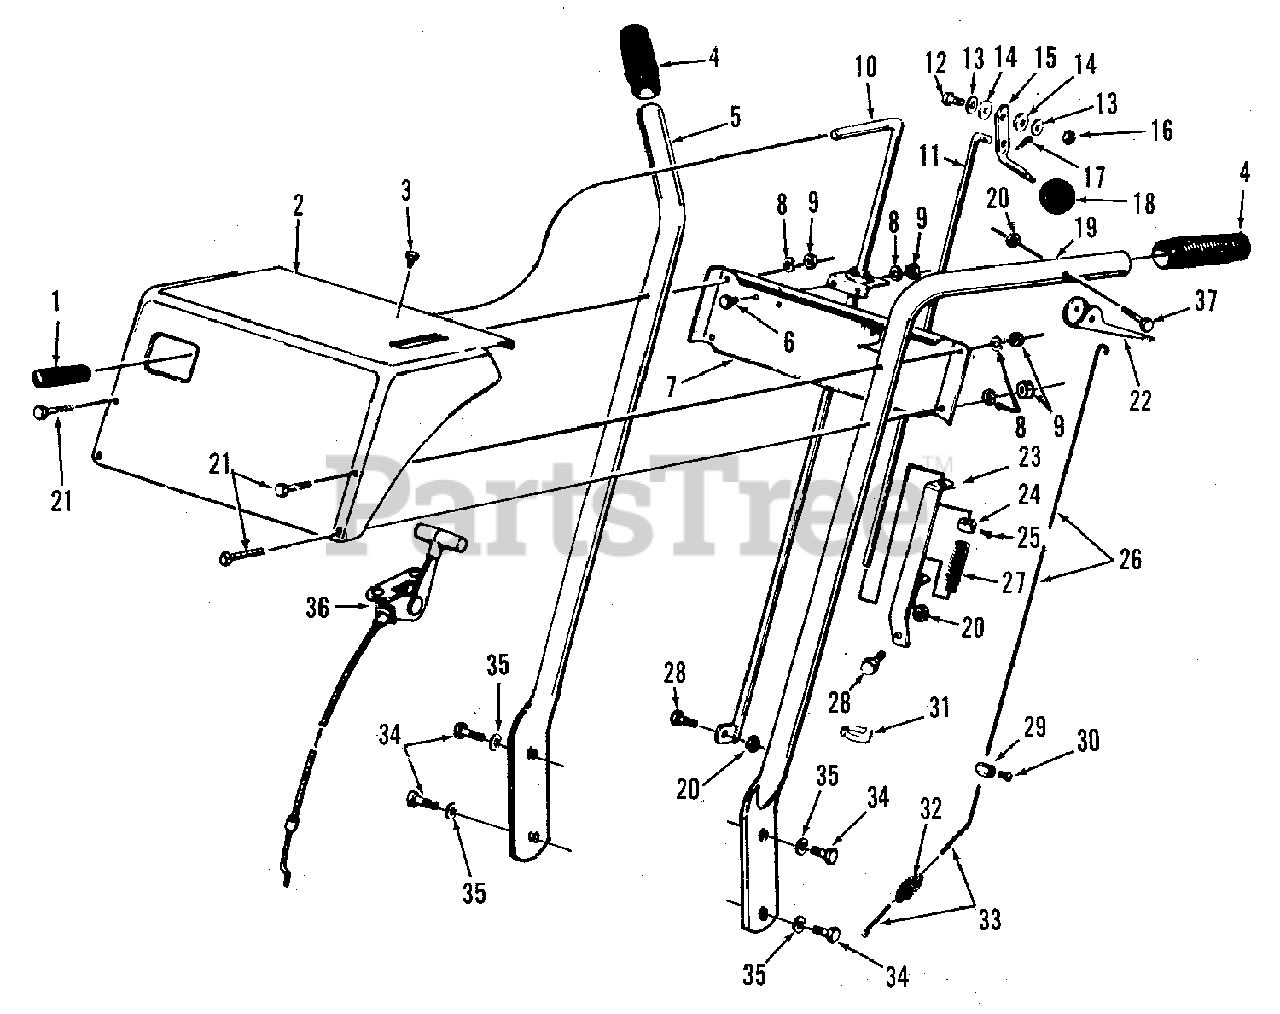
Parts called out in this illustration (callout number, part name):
1	GRIP, Handle
2	CONTROL HOUSING ASSEMBLY
3	SCREW, Hex, Self-Tapping, 1/4-20 x 1/2
5	HANDLE, Rear, R.H.
6	SCREW, Hex Cap, 1/4-20 x 1/2
7	COVER, Handle
8	WASHER, Lock, 1/4"
9	NUT, Full Hex, 1/4-20
10	SHIFT ROD ASSEMBLY
12	SCREW, Hex Cap, 5/16-18 x 7/8
13	WASHER, Flat, 1/4"
14	WASHER, Special
15	HANDLE, Auger Clutch
16	NUT, Elastic Stop, 5/16-18
17	PIN, cotter, 3/32 x 3/4
19	HANDLE, Rear, L.H.
20	NUT, Full, Hex Lock, 1/4-20
21	SCREW, Hex Cap, 1/4-20 x 1-1/2
22	GRIP, Clutch
23	GUIDE ASSEMBLY
25	SCREW, Set, 1/4-20 x 3/8"
26	EXTENSION, Spring
28	SCREW, Hex Cap, 1/4-20 x 1
30	SCREW, Round Head, 10-24 x 3/8
33	WIRE, Extension
34	SCREW, Hex Cap, 5/16-18 x 7/8
35	WASHER, Lock, 5/16"
36	THROTTLE CONTROL ASSEMBLY
37	SCREW, Cap, 1/4-20 x 3/4
